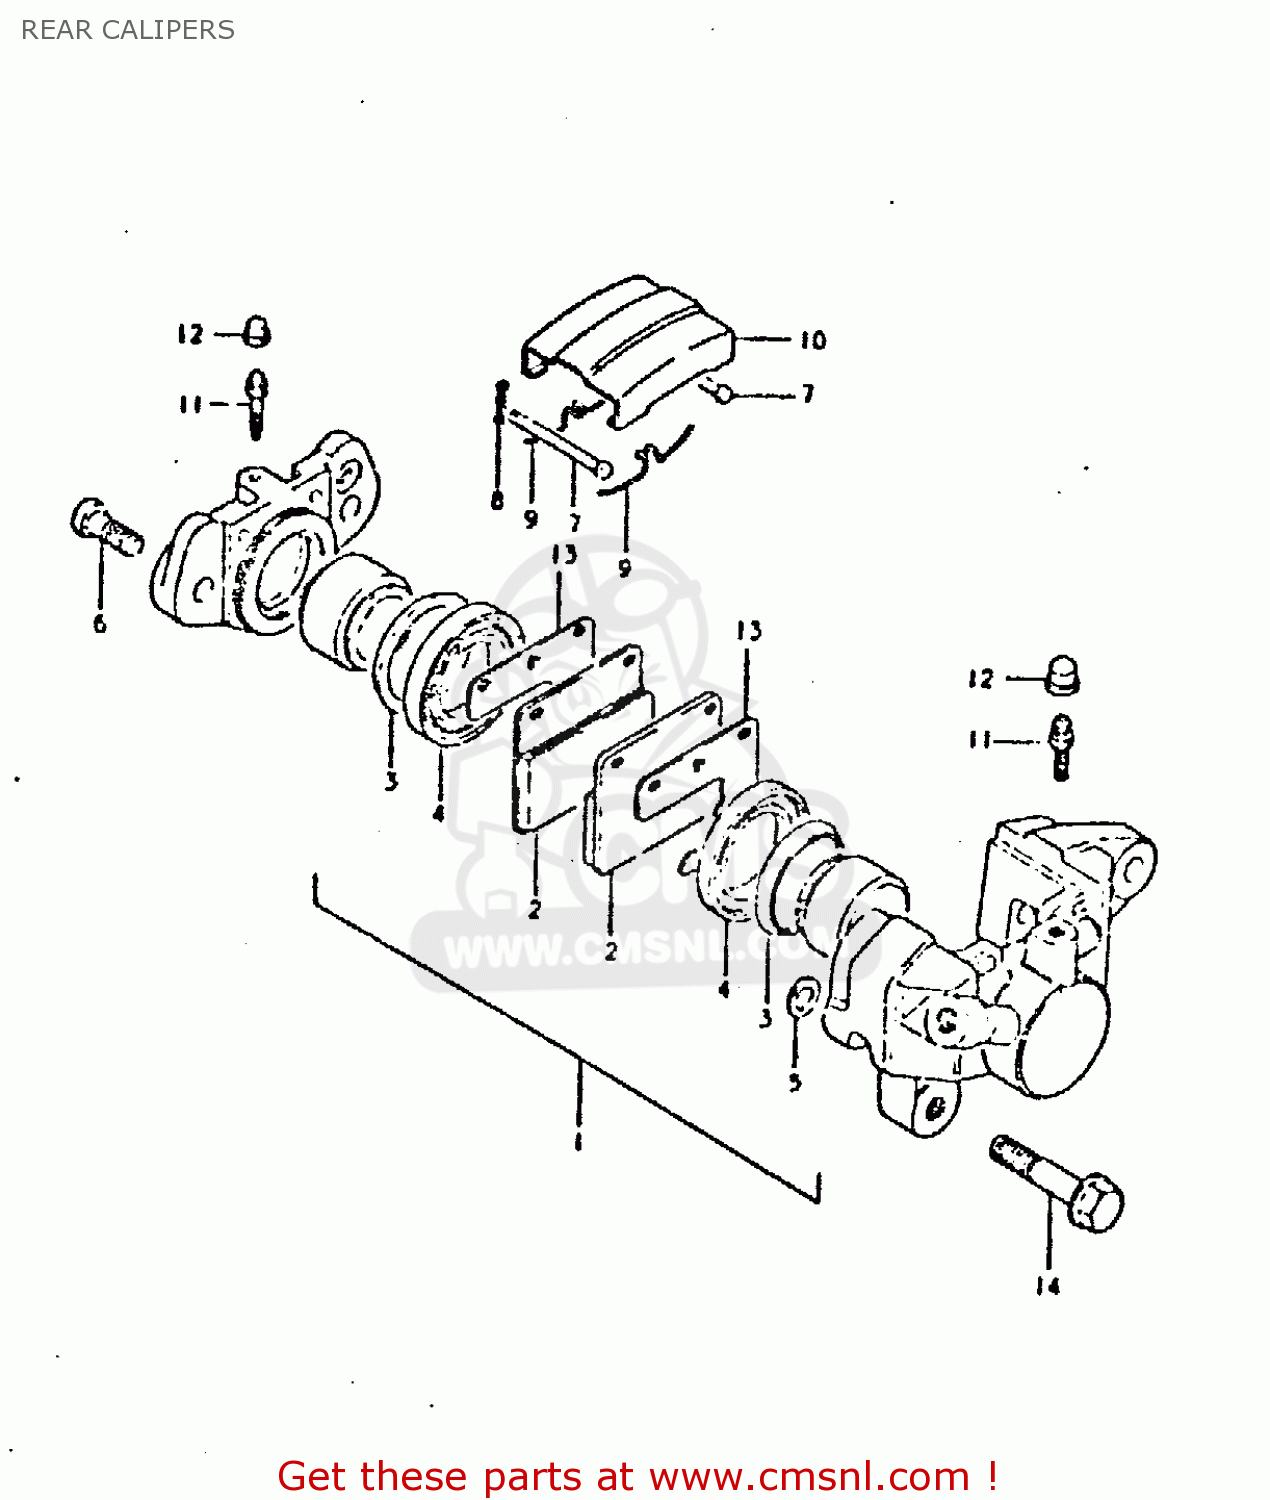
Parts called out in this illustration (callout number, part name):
1	PISTON SET
2	PAD,BRAKE
3	SEAL,PISTON
4	BOOT,PISTON
5	SEAL,PISTON
6	BOLT,HOUSING
7	PIN,PAD
8	CLIP,PAD PIN
9	SPRING
10	COVER,DUST
11	BLEEDER
12	CAP,BREATHER
13	SHIM,RR CALIPER
14	BOLT
